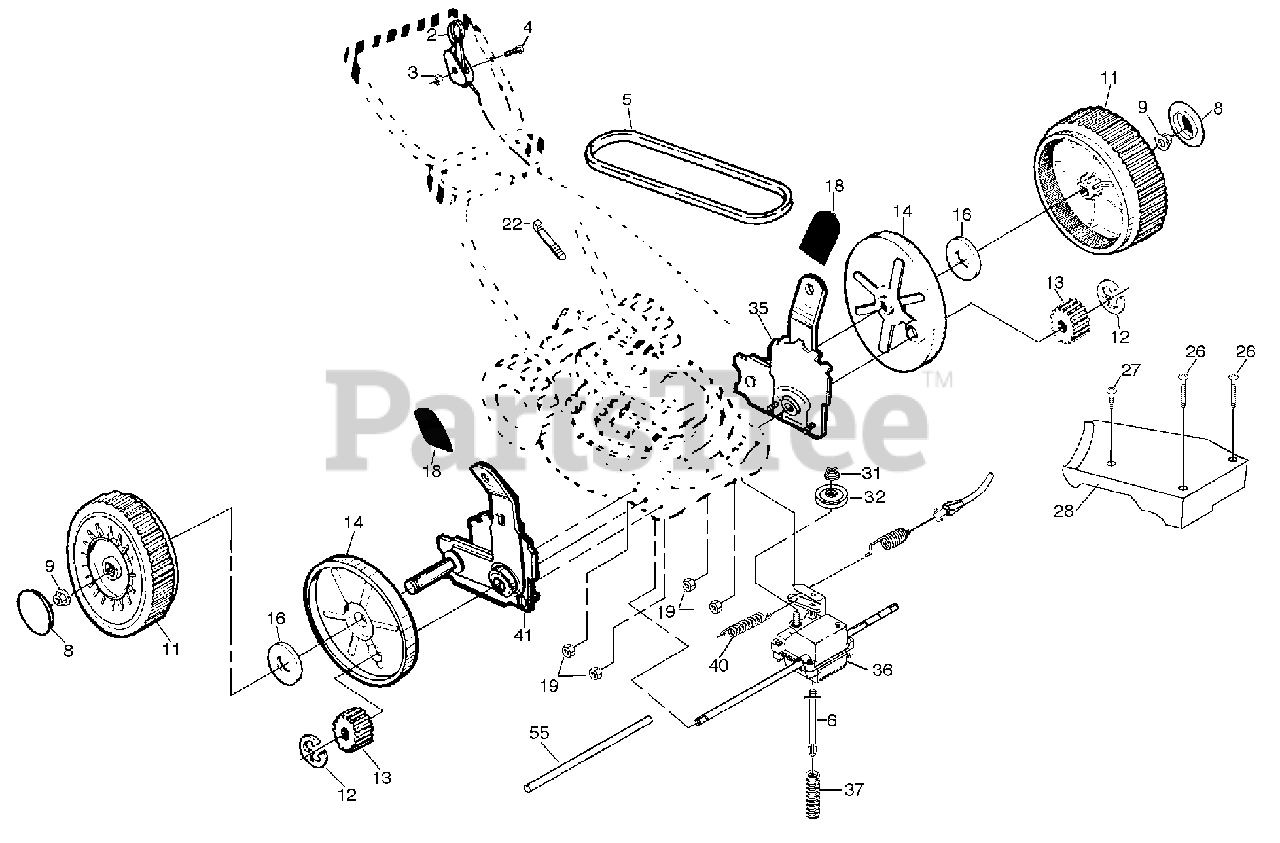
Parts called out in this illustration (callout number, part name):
1	Lower Handle
2	Rope Guide
3	Locknut 1/4-20
4	Handle Bolt
5	Control Bar
6	Wire Ties
7	Hex Washer Head Screw 1/4-20 x 2-1/8
8	Throttle Control
10	Engine Zone Control Cable
11	Upper Handle
12	Hairpin Cotter
13	Handle Knobs
14	Rear Skirt
15	Hex Head Screw
16	Handle Bracket Assembly (Right)
17	Handle Bracket Assembly (Left)
18	Screw 5/16-18 x 3/4
20	Debris Shield
21	Locknut
22	Wheel Adjusting Bracket
23	Spacer
24	Skirt Bracket
25	Selector Spring
26	Selector Knob
27	Axle Arm Assembly
28	Belleville Washer
29	Shoulder Bolt 3/8-16
30	Wheel & Tire Assembly (Rear)
31	Flanged Locknut 3/8-16
32	Flat Washer
33	Wheel Support Bracket (RT)
34	Wheel Support Bracket (LT)
35	Screw
36	Thread Rolling Screw 3/8-16 x 1
39	Front Baffle Kit
40	Mower Housing Kit
43	Hex Head Screw 3/8-24 x 1-3/8 Gr. 8
44	Helical Washer 3/8
45	Hardened Washer
46	22" Blade
47	Blade Adapter
48	Hinge Rod
49	Housing Bracket
51	Torsion Spring
54	Discharge Guard
55	Hi-Pro Key
57	Engine Pulley
58	Cable Clamp
59	Screw #10 x 5/8
61	Danger Decal
65	Bolt
66	Nut
67	Support Rod
68	Screw hex Tap. 1/4/20
69	Wave Washer
70	Pop Rivet
70	Warning Decal
70	Operator's Manual (English)
70	Operator's Manual (French)
70	Repair Parts Manual
70	Grass Catcher
